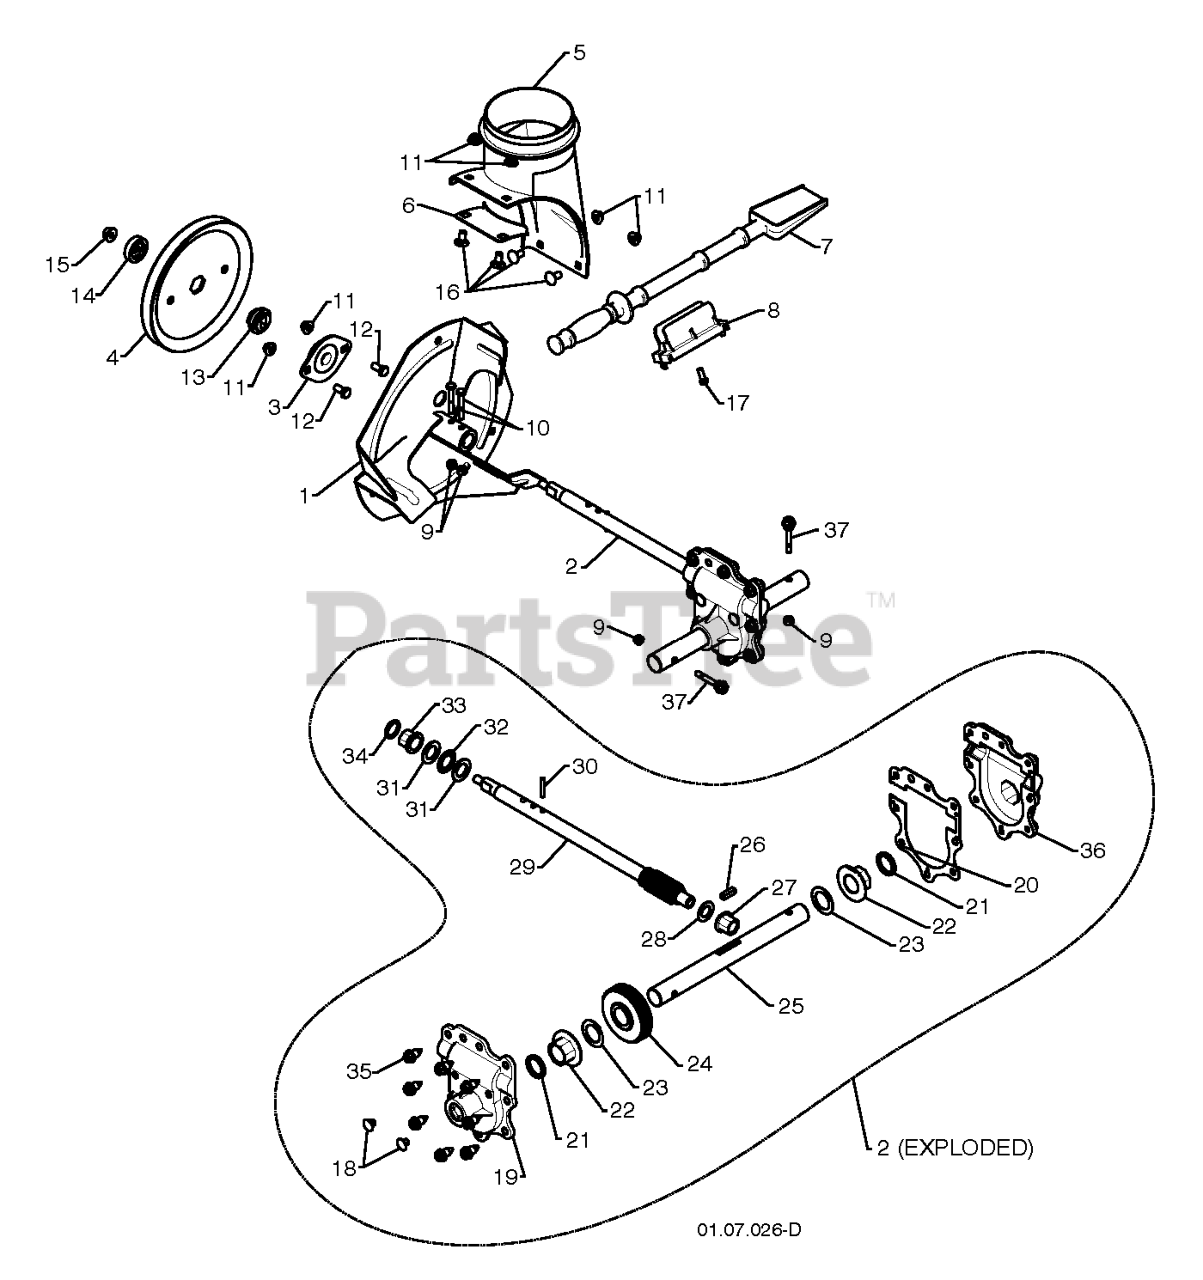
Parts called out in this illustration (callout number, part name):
1	Housing Asm. Mower 107 CRD
2	RP BOLT 5/16-18 X3/4 ZN/YEL GR
5	RETAINER-SPRNG RB
6	BAR.SWAY.92.CRD
8	BOLT.3/8-24X1.25 GR8
9	LOCKWASHER
11	BLADE.3N1.LH.CRD
13	SHAFT ASM VENT
14	HOUSING.MANDREL.VENTED (MACHD)
16	BLADE.3N1.RH.CRD
19	BOLT SHD 5/16-18
20	BOLT.3/8-24X1.25GR8. LHTHRD
21	LOCKNUT
22	BRACKET.IDLER.RR.107.CRD
24	BRACKET
25	BRACKET RF
26	SUPPORT
28	BRACKET
30	SCREW, WASHER HEAD
31	WASHER.SPACER.MANDREL
32	PULLEY.MANDREL.4.80 PD.2006
33	NUT.FLANGE.LOCK.TOP
34	BRACKET
35	BRACKET
36	PULLEY.IDLER.4.25
41	NUT LOCK FLG 3/8-16 UNC
45	COVER.MANDREL.RH.CRD
46	SCREW.1/4-20X5/8
55	ARM.IDLER.107.CRD
61	SPRING
68	HEX-BELT 107 MOWER
69	SHAFT.ASM.W/LWR.BRG.RH.THREAD
84	KEEPER, BELT IDLER
116	BOLT.SHOULDER.3/8-16X3-5/8.
117	RP WHEEL. GUAGE RALLY
118	NUT LOCK FLG 3/8-16 UNC
119	WASHER
124	BOLT.3/8-16X1.50
130	BOLT.CARR.SQNK.5/16-18UNC.X3/4
131	CHUTE BAGGER
163	BLADE.CROSS.RH.CRD.107
164	BRNG T
